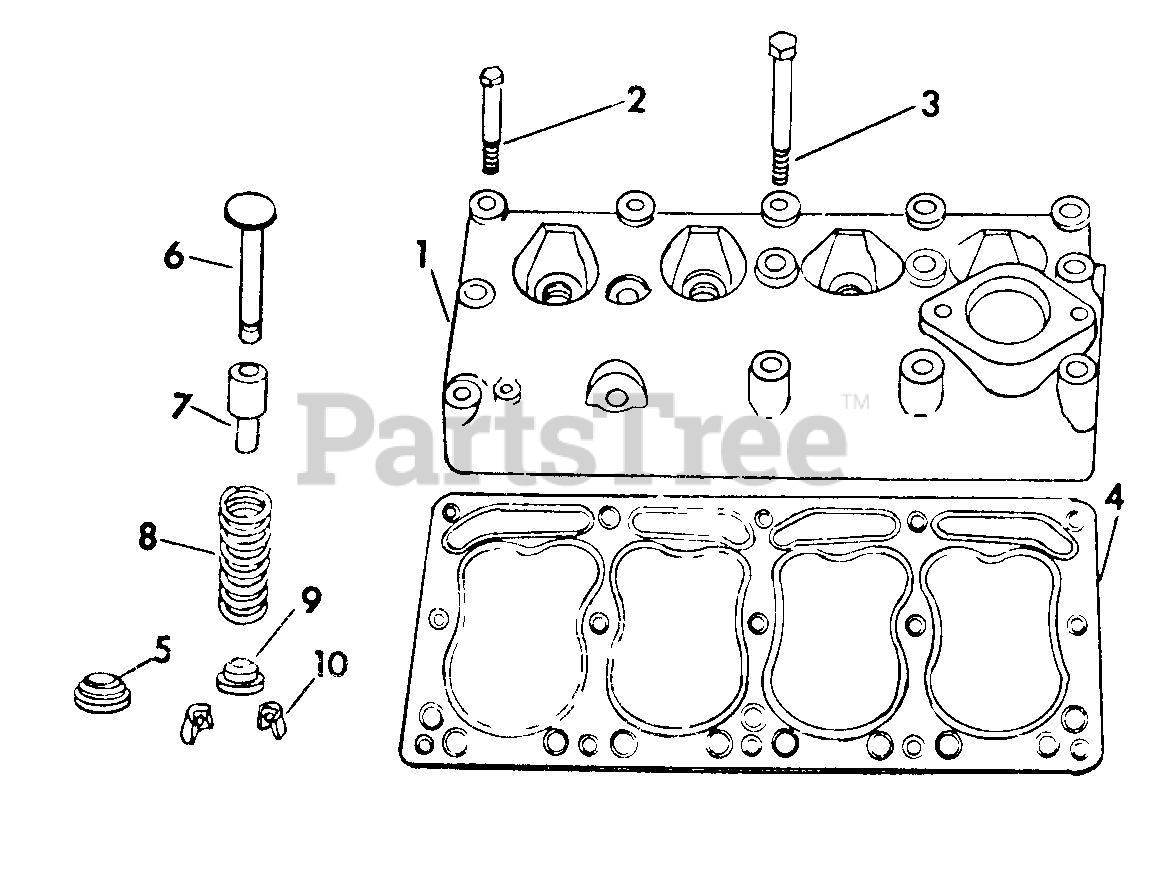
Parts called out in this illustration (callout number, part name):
1	HEAD, CYLINDER
2	SCREW, CYL HEAD SHORT CAP
3	SCREW, CYL HEAD LONG CAP
4	GASKET, CYLINDER HEAD
5	ROTOCAP, EXHAUST VALVE
6	VALVE, INTAKE
6	VALVE, EXHAUST
7	GUIDE, VALVE
8	SPRING, VALVE
8	SPRING, EXHAUST VALVE
9	SEAT, VALVE SPRING
10	KEY, VALVE SPRING SEAT
